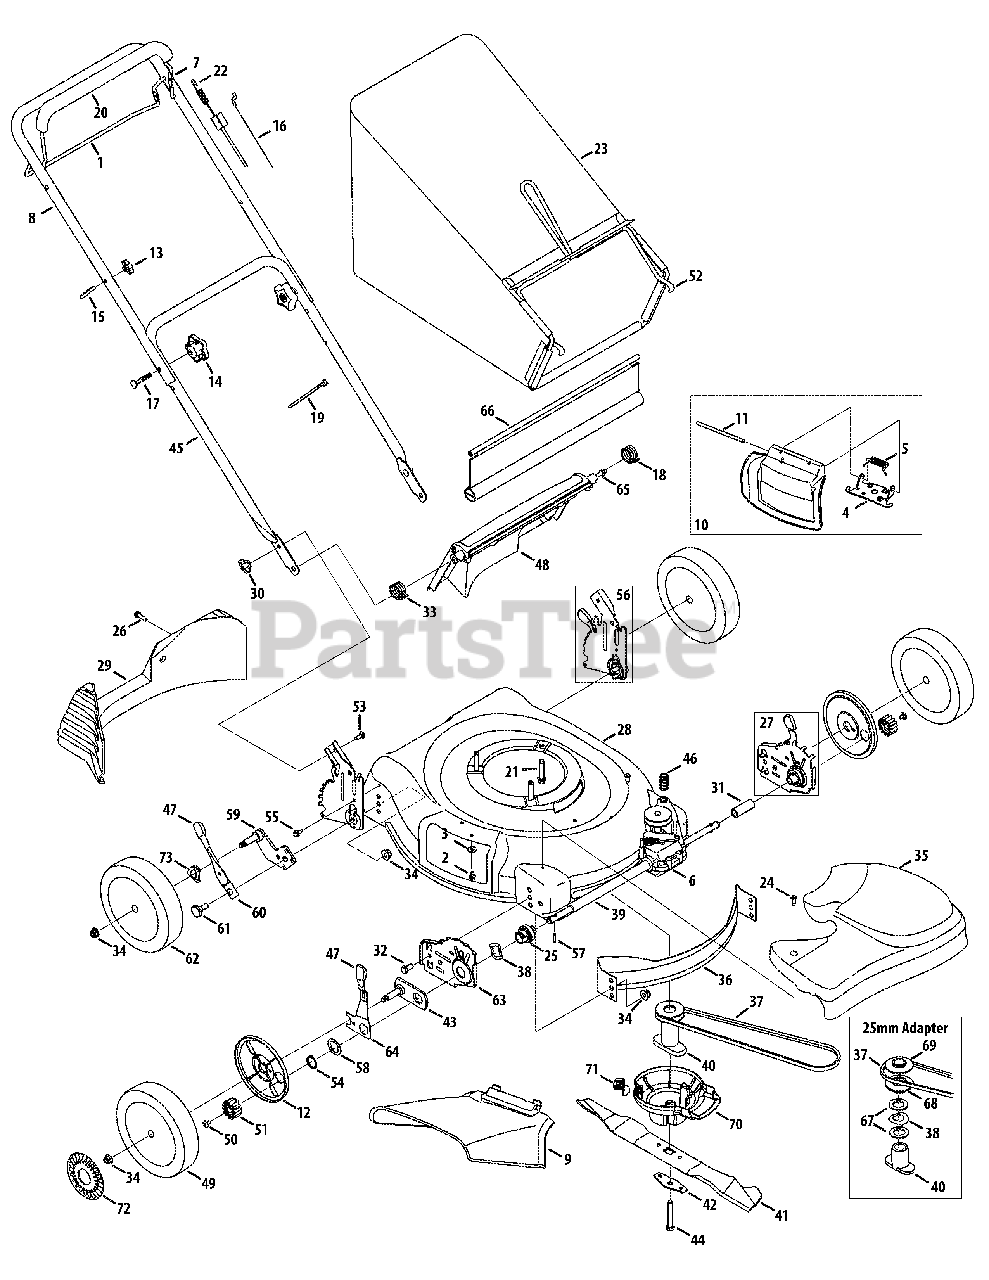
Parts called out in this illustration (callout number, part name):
1	Drive Control
2	TT Screw 1/4-20 x 0.5
3	Bell Washer .265 x 0.75
4	Deflector Chute Adapter
5	Torsion Spring
6	Transmission Assembly
9	Chute Deflector
10	Mulch Plug Complete
11	Hinge Pin
12	Wheel Dust Cap
13	Handle Knob
14	Star Knob
15	Eye Bolt
16	Control Cable - 40.75''
17	Carriage Bolt 5/16-18 x 2.0
18	Torsion Spring - LH
19	Cable Tie
20	Bail Cover
21	Self - Tapping Sems Screw
22	Drive Cable - 51''
23	Grassbag
24	Shoulder Screw #12-24
25	Front Bearing Assembly
26	Screw, 1/4-15 x 1.000
27	Height Adjustment Assembly - RH
27	Height Adjustment Assembly - LH
30	Wing Nut
31	Sleeve Spacer 1.4''
32	Hex Screw, 3/8-16 x .75
33	Torsion Spring - RH
34	Flange Lock Nut, 3/8-16
35	Transmission Cover - Black
35	Transmission Cover - Gray
36	Front Baffle
37	V-Belt
38	Wave Washer
39	Sleeve Spacer 8.985''
40	One Piece Blade Adapter
40	Blade Adapter, 25mm
41	21'' Mulching Blade
42	Blade Bell Support
43	Pivot Plate Assembly
44	Hex Screw, 3/8-24 x 2.50
46	Belt Tension Spring
47	Adjustment Knob
48	Rear Discharge Door
49	Front Wheel, 8 x 2.125, Zag
50	Screw, 1/4-20 x .390
51	Gear 14T RH FWD
51	Gear 14T LH FWD
53	Carriage Bolt 1/4-20
54	Snap Ring
55	TT Screw w/Washer 1/4-20 x .625
56	Handle Bracket Assembly - RH
56	Handle Bracket Assembly - LH
57	Dowel Pin
58	Washer
59	Pivot Arm Assembly - RH
59	Pivot Arm Assembly - LH
60	Rear Spring Lever
61	Shoulder Screw .500 Dia x .434
62	Rear Wheel, 8 x 2.125, Zag w/BB
63	Rear Wheel, 8 x 2.125, Zag
63	Height Adjuster Plate - RH
63	Height Adjuster Plate - LH
64	Front Lever - RH
64	Front Lever - LH
65	Pivot Rod
66	Rear Trailing Shield
67	Washer, Flat, 1.031 x 1.620 x .095
68	Pulley, Half
69	Pulley, Half
70	Engine Baffle
71	Engine Baffle Bracket
72	Hub Cap
73	Washer, Wave .510 x .750 x .017
